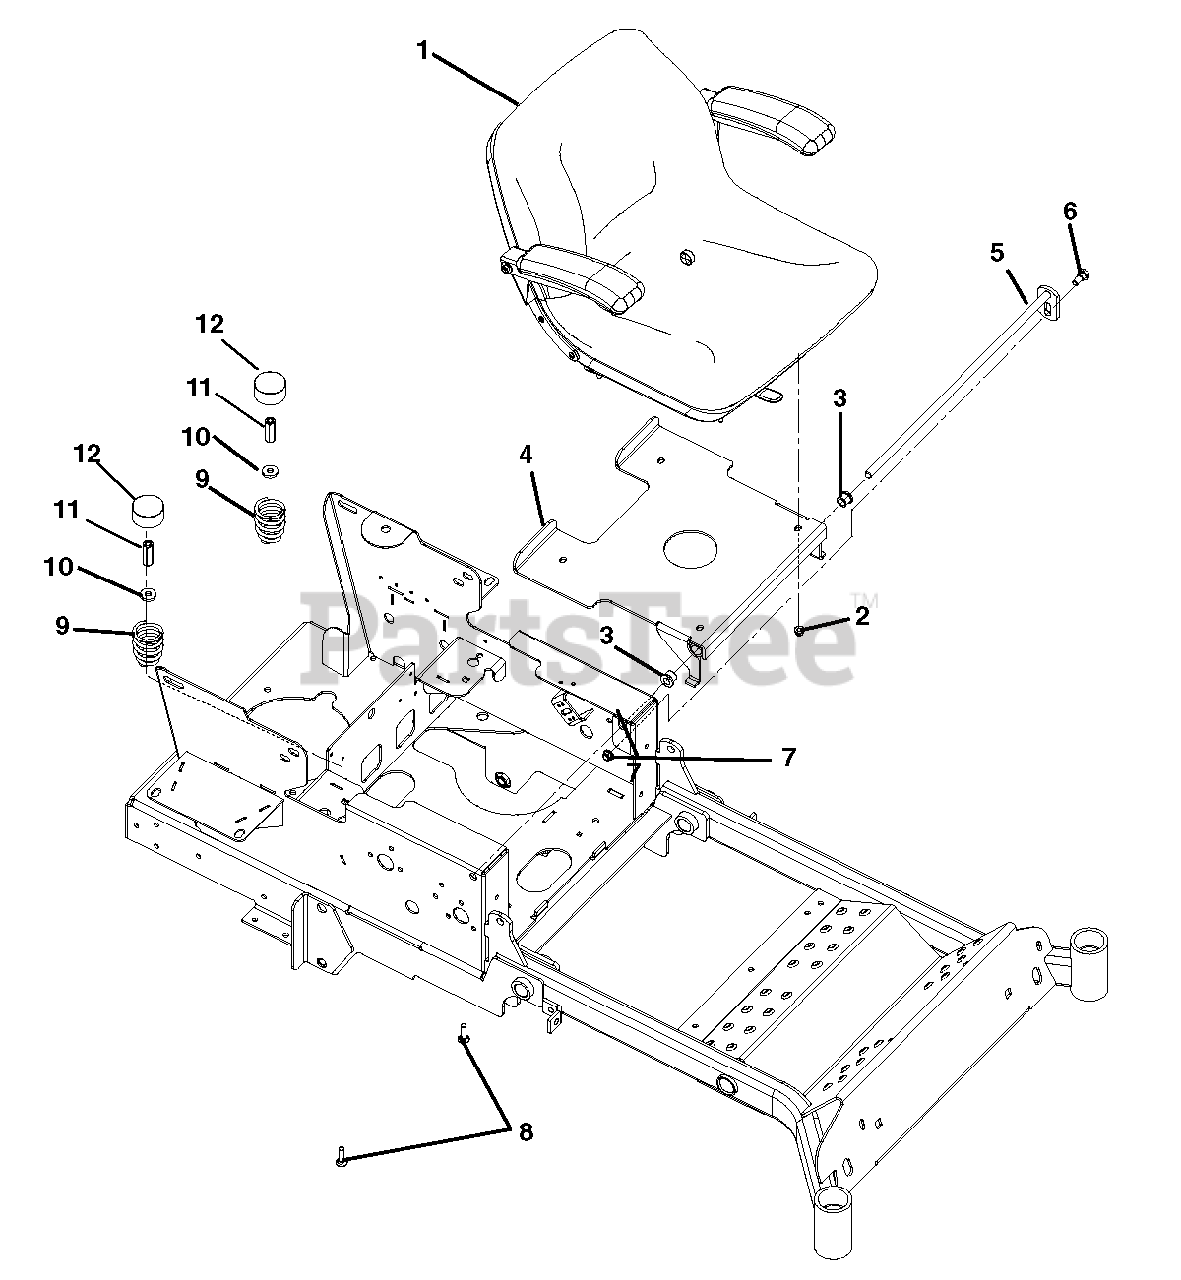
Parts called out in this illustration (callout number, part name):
1	Assembly, Seat with Armrests
2	Nut, Nyloc Flange 5/16-18
3	Bushing, Flange .515 x .750 x .745 x 1.00
4	Weldment, Seat Plate
5	Weldment, Seat Shaft
6	Bolt, Shoulder EP .38-16 x .30 Hex
7	Nut, .38-16 Nyloc Flange
8	Bolt, Round Head Square Neck .38-16 x 1.25 Grade 5
9	Spring, Seat
10	Washer, Flat-Steel .406 x 1.00 x .188
11	Nut, Coupling .375-16 x 1.75
